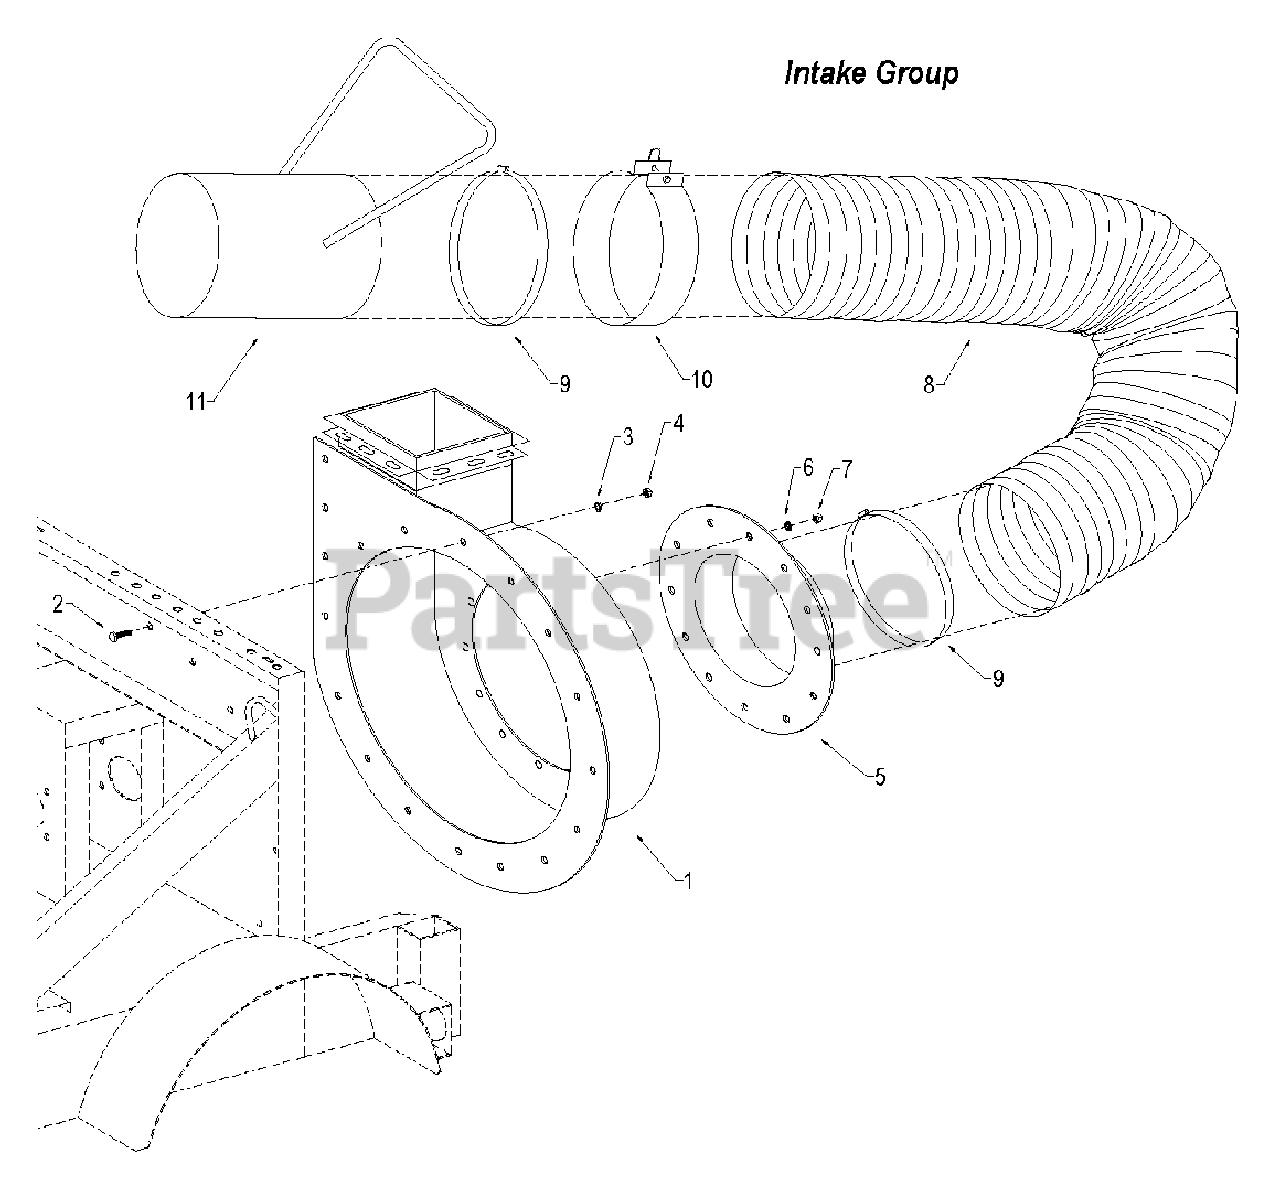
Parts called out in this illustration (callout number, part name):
1	Housing, impeller – complete with liner kit below
2	Bolt, hex - 3/8-16 x 1"
3	Washer, lock - 3/8"
4	Nut, hex - 3/8-16
5	Flange, intake, 16 90 degree
6	Washer, lock - 1/2
7	Nut, hex - 1/2-13
8	Hose, intake - 16" x 7'
9	Clamp, hose - 16"
10	Band, hose support – 16 – with hardware *
11	Nozzle, intake - 16"
